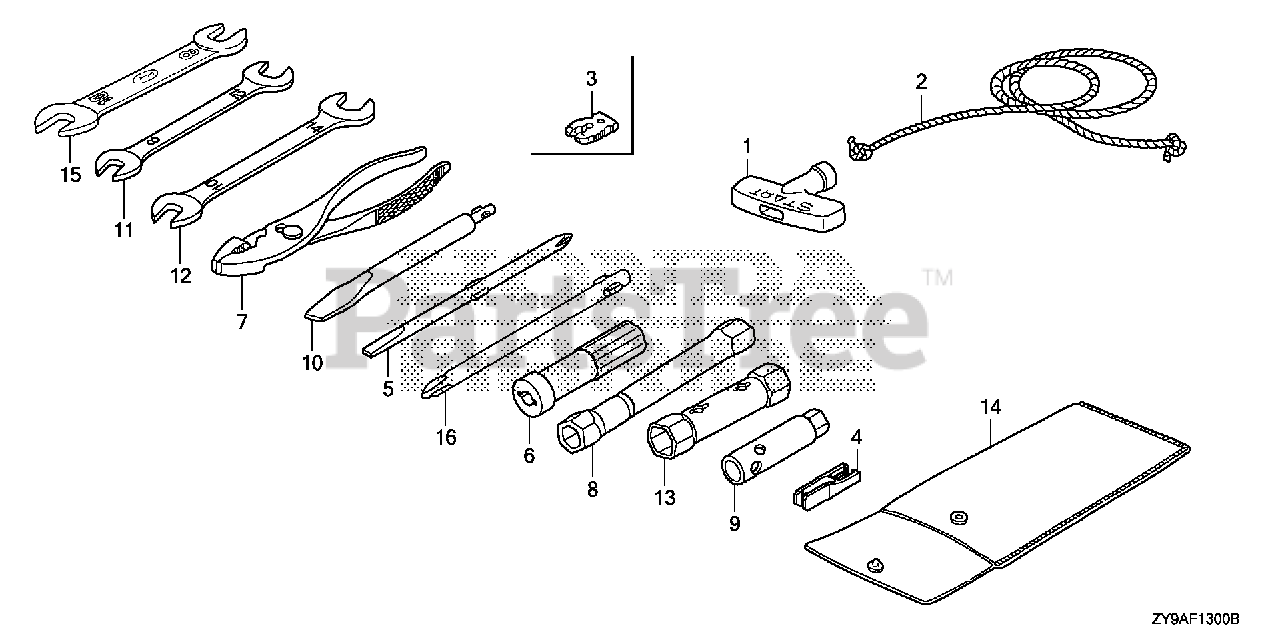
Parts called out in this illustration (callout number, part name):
1	KNOB, RECOIL SRARTER
2	ROPE, RECOIL STARTER (1300MM)
4	PULLER, MINI FUSE (SUMITOMO)
6	GRIP, SCREW DRIVER
8	WRENCH, PLUG
13	WRENCH, BOX (P18X19)
15	SPANNER (8X10)
16	DRIVER 1, PLUS SCREW (NO.2)
